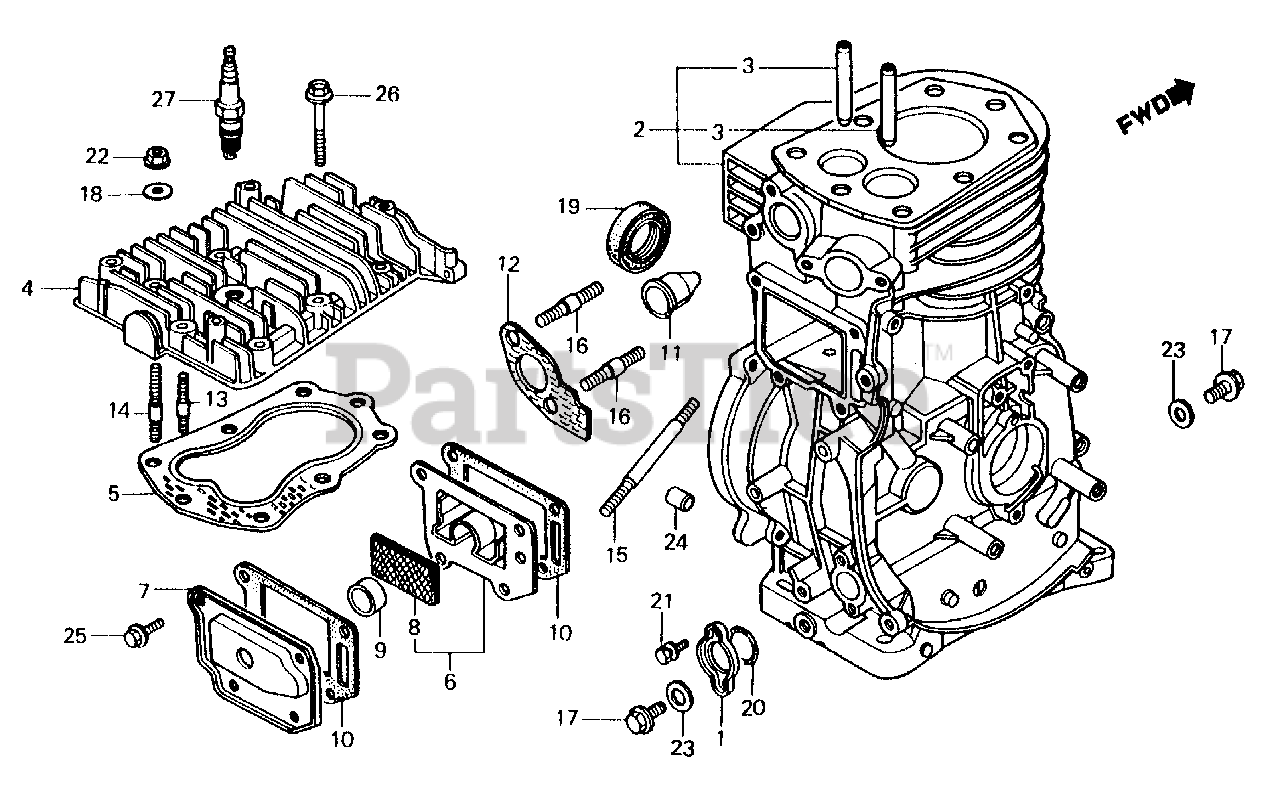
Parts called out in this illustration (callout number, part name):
1	COVER, OIL PAN
2	CYLINDER (NOT AVAILABLE)
3	GUIDE, VALVE
4	CYLINDER HEAD
5	GASKET, CYLINDER HEAD
6	CASE, BREATHER
7	COVER, TAPPET
8	FILTER, BREATHER
9	SEAL, BREATHER
10	GASKET, TAPPET COVER
11	LINER, EX. PIPE
12	GASKET, EX. PIPE
13	BOLT, STUD (M8XM10X63)
14	BOLT, STUD (M8XM10X81)
15	BOLT, STUD (8X104)
16	BOLT, STUD (8X35)
17	BOLT, DRAIN PLUG
18	WASHER (8MM)
19	OIL SEAL (25X41X6)
20	O-RING (27X2.0)
21	BOLT-WASHER (6X12)
22	NUT-WASHER (8MM)
23	WASHER, DRAIN PLUG (12MM)
24	PIN A, DOWEL (8X14)
25	BOLT, FLANGE (6X12)
26	BOLT, FLANGE (8X50) (NOT AVAILABLE)
27	SPARK PLUG (BR-4HS) (NGK)
27	SPARK PLUG (W14F-U) (DENSO)
27	SPARK PLUG (W14FR-U) (DENSO)
